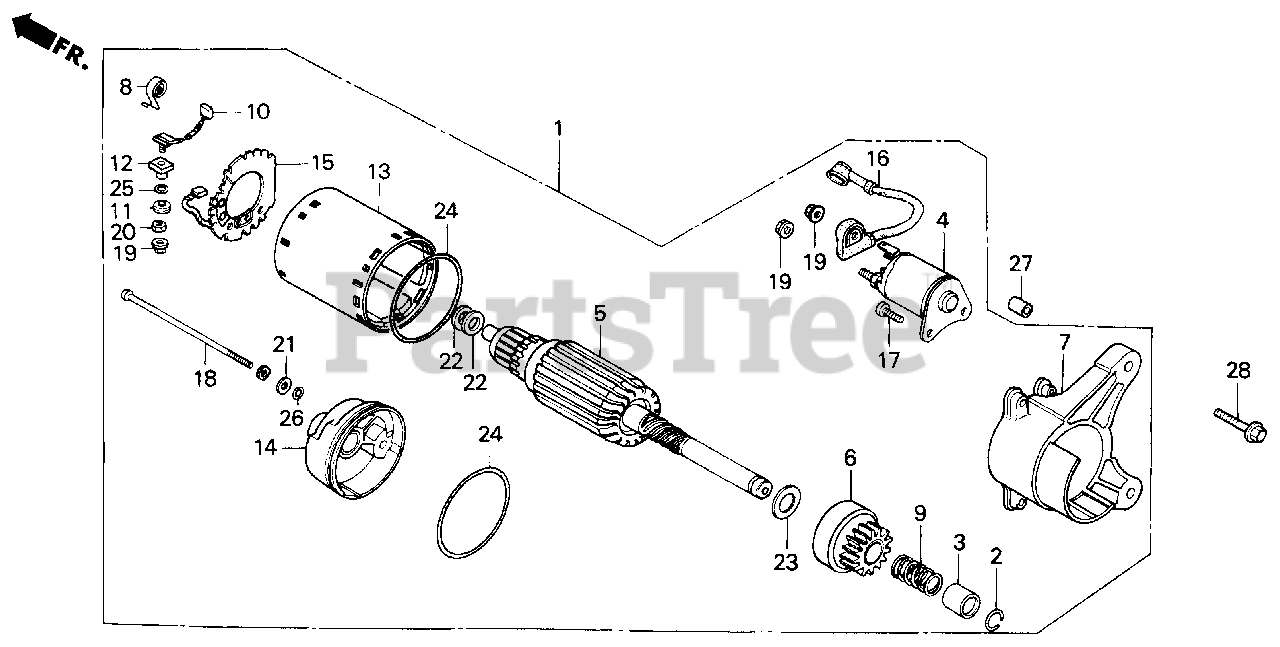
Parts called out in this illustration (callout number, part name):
1	MOTOR ASSY., STARTER
2	RING, SNAP
3	COLLAR, CLUTCH
4	CONTACTOR ASSY.
6	CLUTCH, OVERRUNNING
7	HOUSING, DRIVE SIDE
8	SPRING, BRUSH
11	BUSHING, INSULATION
12	BUSHING, INSULATION
14	FRAME, STARTER END
15	PLATE, BRUSH HOLDER
16	WIRE, WATER COVER
17	BOLT
18	BOLT, THROUGH (NOT AVAILABLE)
18	BOLT, THROUGH
21	WASHER, STEEL PLATE
22	WASHER
27	PIN A, DOWEL (10X16)
28	BOLT, FLANGE (8X40)
